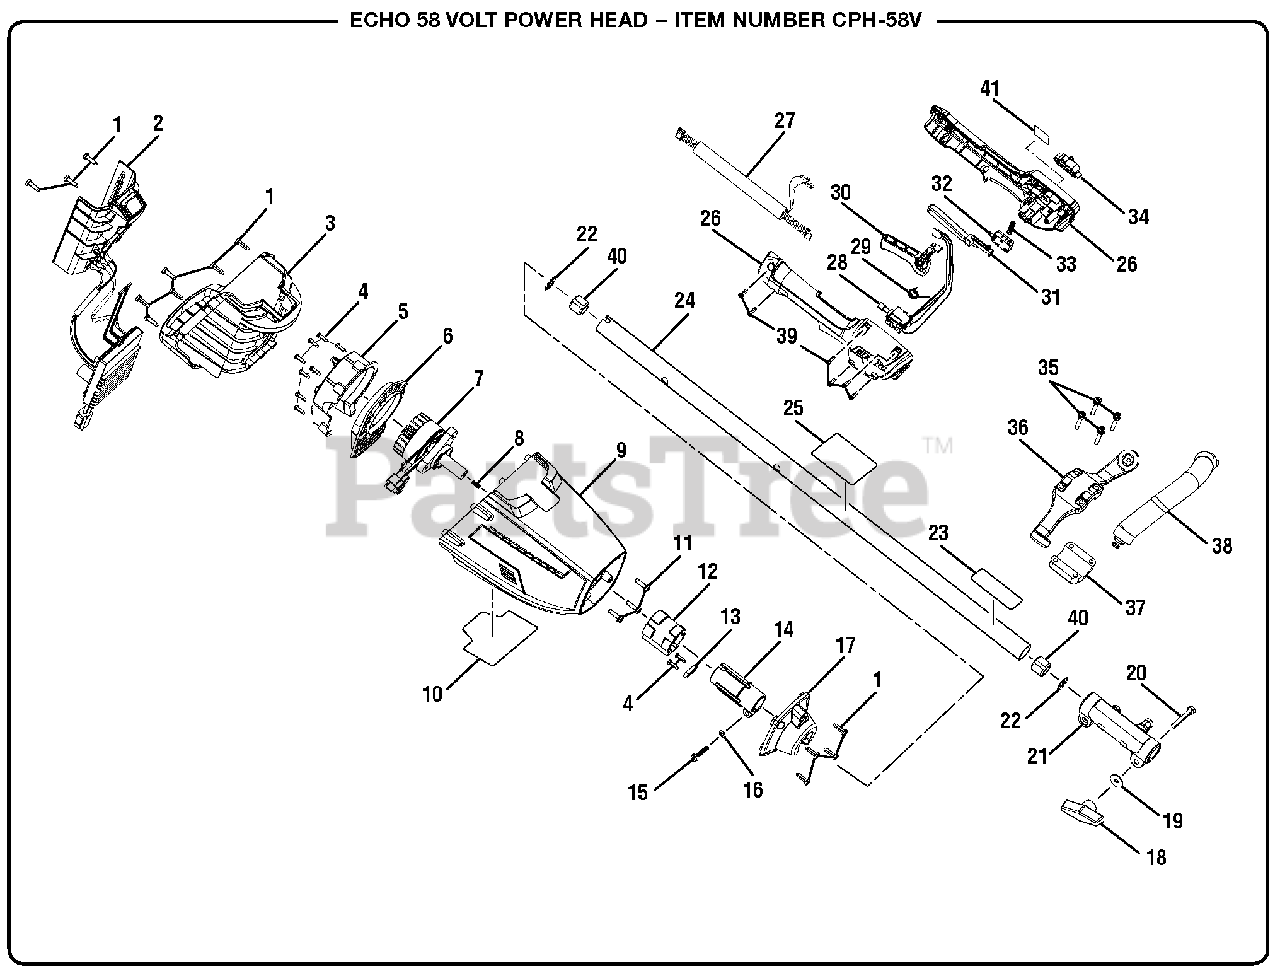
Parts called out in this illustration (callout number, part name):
1	Screw (M5 x 18 mm, T25 Torx Pan Hd.)
2	Circuit Board and Battery Carriage Assembly
3	Battery Mounting Box
4	Screw (M4 x 13.5 mm, T15 Torx Pan Hd.)
5	Motor Cover
6	Motor Volute
7	Motor and Pinion Assembly
8	Compression Spring
9	Motor Housing Assembly
10	Data Label
11	Screw (M5 x 15mm, T25 Torx Flange Hd.)
12	Ring (Rubber)
13	Wire Clamp
14	COUPLER
15	Screw (M5 x 26 mm, T25 Torx Pan Hd.)
16	Washer (ID5.2 x OD10 x 1t)
17	End Cap
18	Knob Assembly
19	Washer (ID6.6 x OD20 x t1.6)
20	Screw (M6 x 40 mm, Hex Hd.)
21	Coupler Assembly
22	Spring Washer (ID11 x OD23 x 1.54t)
23	Warning Icon Label
24	Upper Boom Assembly
25	Boom Label
26	Rear Handle Housing Assembly
27	Wire Assembly
28	Variable Signal Switch
29	Torsion Spring
30	Switch Trigger (Button)
31	Lock-Out Button
32	Hi-Lo Switch
33	Compression Spring (Trigger)
34	Switch Actuator
35	Screw w/Washers (M5 x 26 mm, Pan Hd.)
36	Bracket (Handle)
37	Clamp (Auxiliary Handle)
38	Front Handle Assembly
39	Screw (M4 x 14 mm, T20 Torx Pan Hd.)
41	Throttle Label
